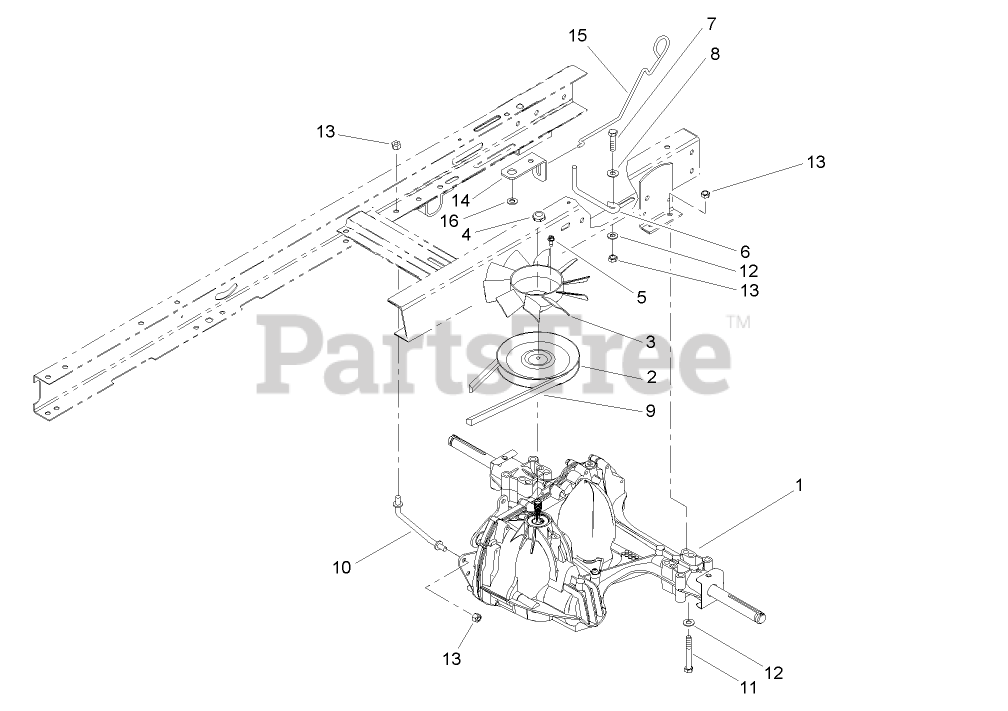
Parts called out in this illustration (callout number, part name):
1	TRANSAXLE ASM
2	PULLEY
4	NUT-LOCK, NI
5	SCREW-HWH
6	GUIDE-BELT
7	SCREW-HH
8	WASHER-PIVOT
9	V-BELT
10	STRAP-TORQUE
11	SCREW-HH
12	WASHER-PLAIN
13	NUT-LOCK, NI
14	BRACKET-BYPASS
15	ROD-BYPASS
16	WASHER-FLAT
